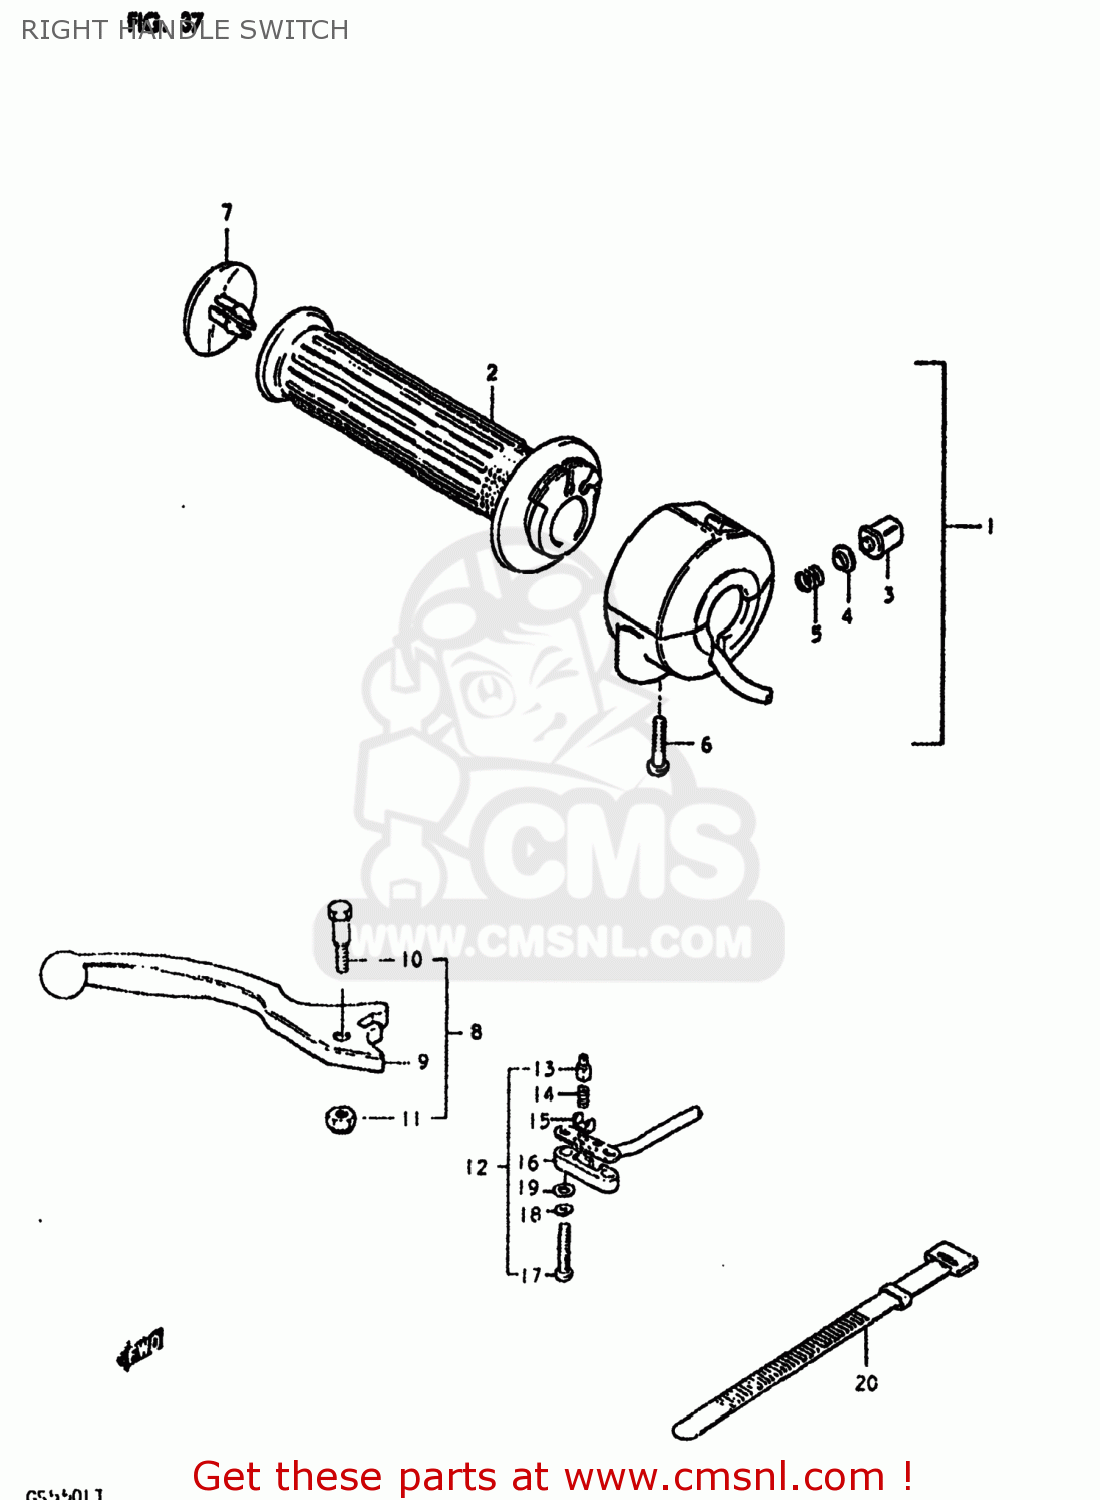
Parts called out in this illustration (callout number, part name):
1	CASE ASSEMBLY,THROTTLE
2	GRIP,THROTTLE
3	BUTTON,HORN
4	CONTACT
5	SPRING
6	SCREW
7	CAP,GRIP END
8	LEVER ASSEMBLY,BRAKE
9	LEVER,BRAKE
10	BOLT
11	NUT 6MM
12	SWITCH ASSEMBLY
13	HOLDER
14	SPRING
15	PLATE
16	COVER,FR BK TERMINAL BASE
17	SCREW
18	LOCK WASHER
19	WASHER
20	CLAMP(L:120)
